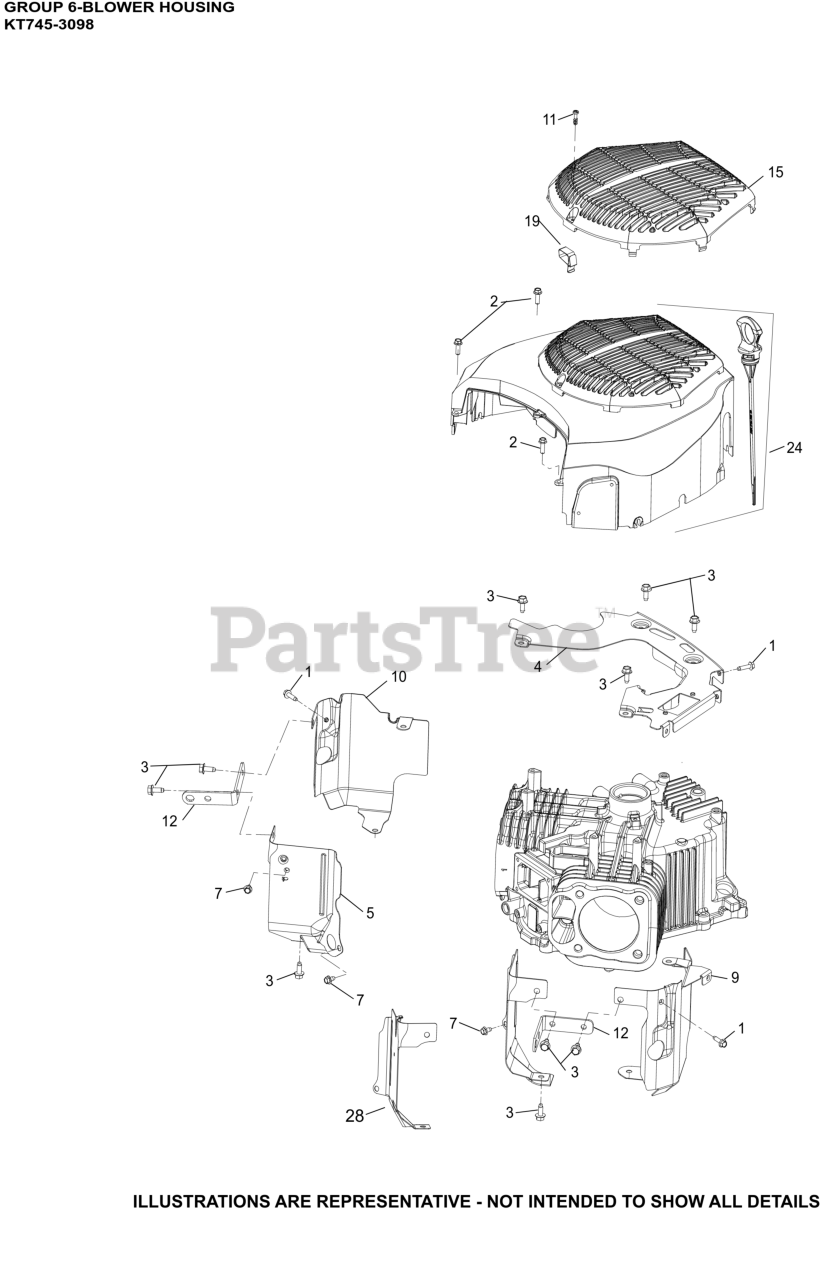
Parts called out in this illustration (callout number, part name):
1	SCREW, THD FRM-USE 25 086 473-S
2	SCREW, HI-LOW
3	SCREW, THREAD FORMING
4	PLATE, BACKING
5	BAFFLE, VALLEY #1
7	SCREW, THREAD FORMING
9	BAFFLE, LEFT BARREL
10	BAFFLE, RIGHT BARREL
11	SCREW, M5-2.42 (PT) THREAD
12	STRAP, LIFTING
15	GUARD, FIXED
19	CLIP, BLOWER HOUSING
24	KIT, BLOWER HOUSING
28	BAFFLE, VALLEY #2
